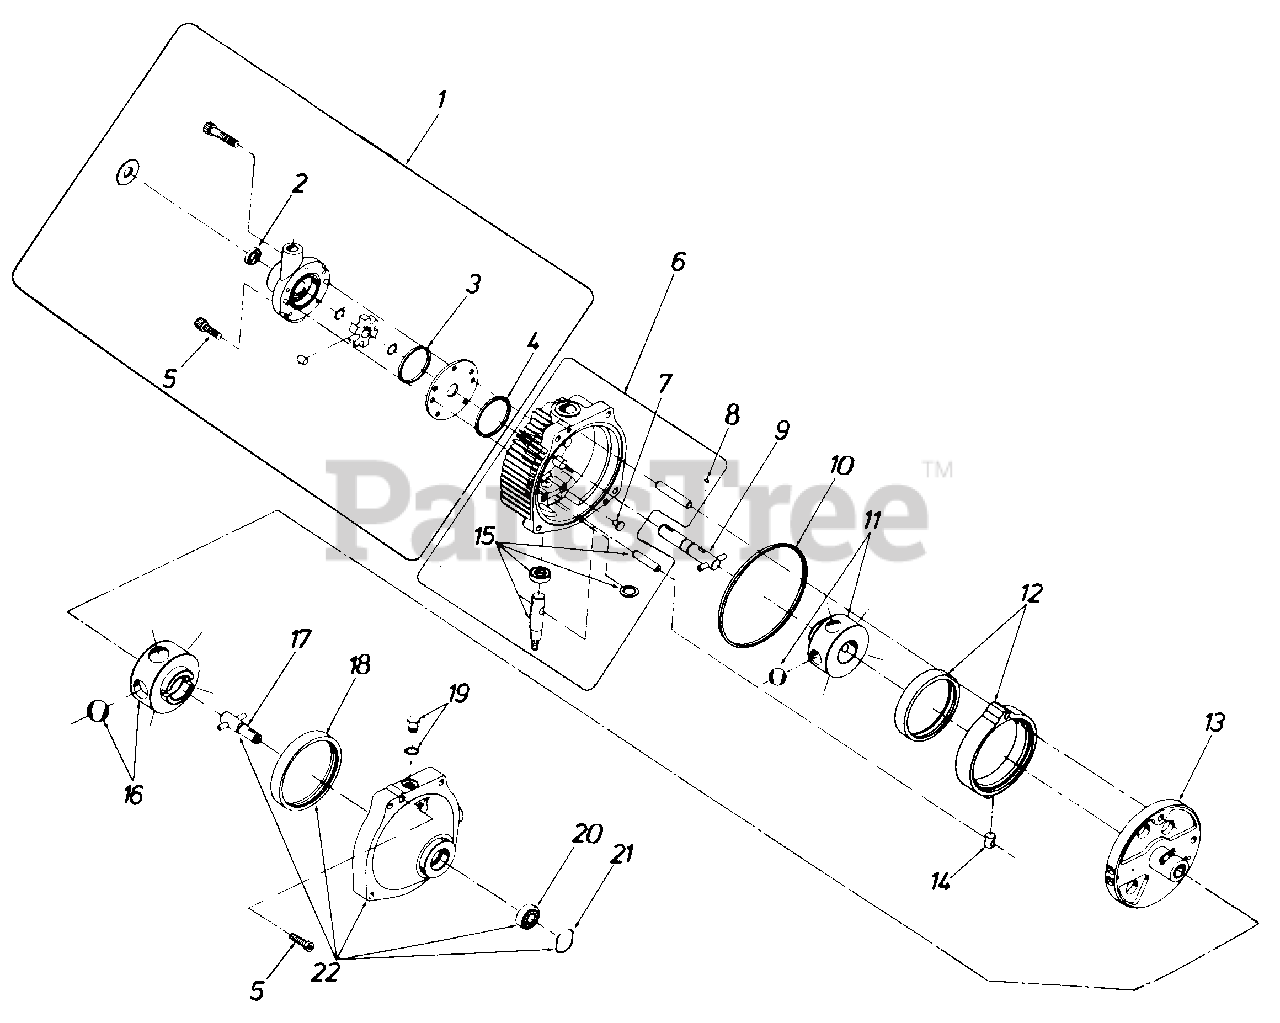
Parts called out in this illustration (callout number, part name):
1	Charge Pump Kit
2	Oil Seal
3	Square Cut Seal Ring .036
4	Square Cut Seal Ring .038
5	Socket Head Cap Screw 5/16-18 x 1.25" Long
6	Cover Subassembly
7	Button
8	Drive Pin
9	Input Shaft Subassembly
10	Square Cut Seal Ring .166
11	Pump Rotor Ball Subassembly
12	Cam Ring Subassembly
13	Pintle Subassembly
14	Cam Ring Insert
15	Control Shaft Kit
16	Motor Rotor Ball Subassembly
17	Output Shaft Subassembly
18	Motor Race
19	O-Ring Plug Subassembly
20	Ball Bearing (Output)
21	Retaining Ring
22	Body Subassembly
